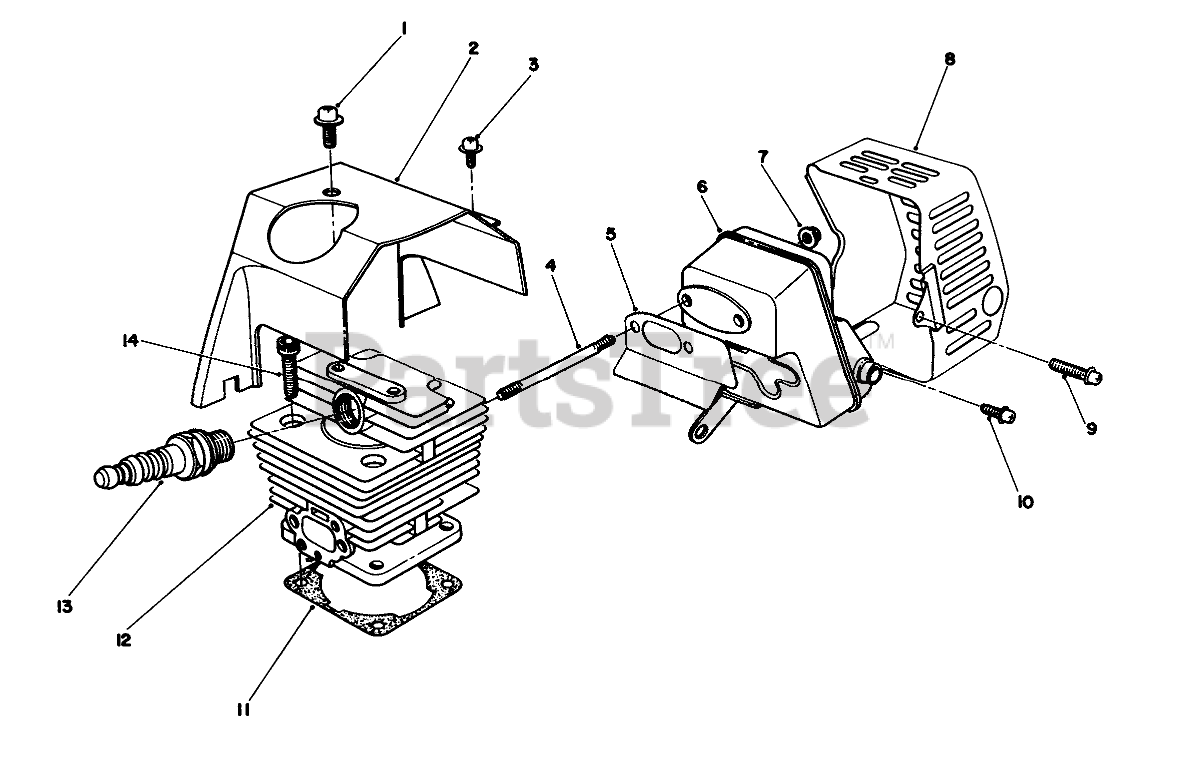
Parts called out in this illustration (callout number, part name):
1	Screw & Dishes
2	COVER,CYLINDER
3	Screw & Washer
4	BOLT,STUD
5	GASKET, MUFFLER
6	MUFFLER
7	NUT, FLANGE
8	COVER, MUFFLER
9	Screw & Washer
10	SCREW & WASHER
11	GASKET,CYLINDER
12	Cylinder (Incl. Ref. #4)
13	SPARK PLUG (NGK)
